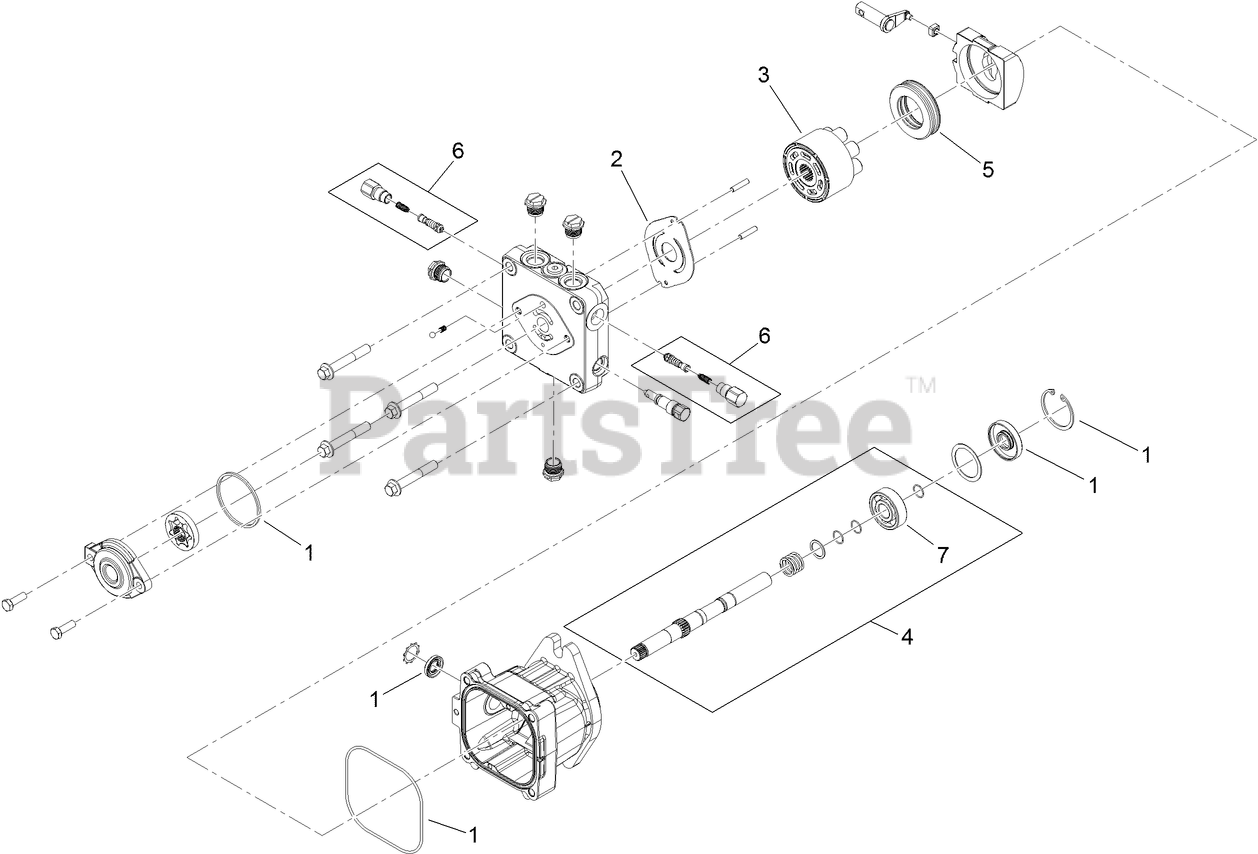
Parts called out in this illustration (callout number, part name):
1	OVERHAUL SEAL KIT
2	PLATE-VALVE
4	INPUT SHAFT KIT
5	THRUST BEARING KIT
7	INPUT BEARING KIT
